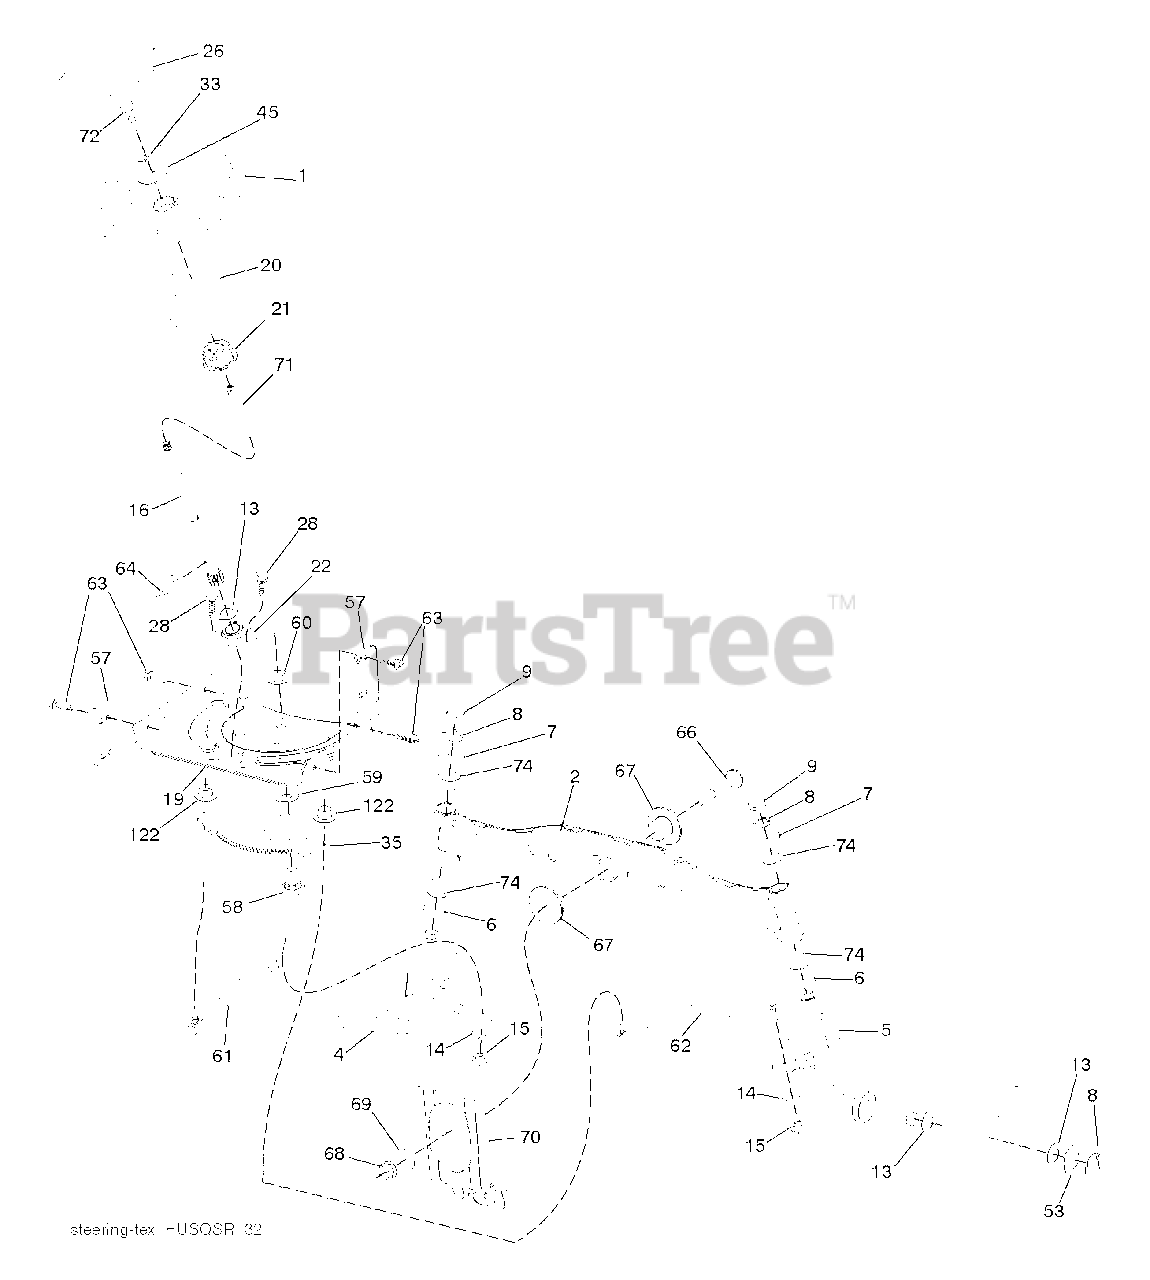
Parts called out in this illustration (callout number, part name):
1	WHEEL.STEER.HUSQ.SR.498.OVMLD
2	AXLE HALF ASM-WELDED
4	SPINDLE.WELDED.LH.15"TEX
5	SPINDLE.WELDED.RH.15"T
6	THRUST WASHER
9	CAP.SPINDLE.BLACK
14	WASHER, LOCK 3/8
15	NUT CROWNLOCK 3/8-24
16	SHAFT.STEER.3/4.PLATED.TEX
19	PLATE.STEER.DDL.NLT/NG
20	STEERING.BOOT.HUSQ.LT
21	ADAPTER, WHEEL STNG..
22	STEERING.SUPT.LOWER.
26	INSERT.CAP.WHL.STRG.HUSQ.PREM
28	SCREW, 3/8-16X3/4
33	LOCKWASHER
35	GEAR.SECTOR.PLATE.DDL.
45	WASHER.11/32
53	WASHER.HARDENED
57	BRACKET.UPSTOP.TEX
58	BOLT.SHOULDER.SECTOR.P
59	WASHER.THURST.SECTOR.S
60	NUT FLANGE LOCK 5/8-11
61	DRAGLINK.LH.BALLSTUD.D
62	DRAGLINK.RH.BALLSTUD.D
63	SCREW
64	RETAINER.CLIP.SPRING.S
66	BOLT HEX FGHD 7/16-14 X 3 SERR
67	BUSHING.PM.FRONT AXLE
68	NUT.LOCK.FLANGE.7/16
69	WASHER.1.5X.505X.118
70	BRKT.DECK.SUSPENSION.F
71	SHAFT.EXTEN.STRG.SPLINE
72	BOLT 5/16-18 X 4 W/PATCH
74	BRNG T
122	CAP.GEAR.SECTOR.TEX
